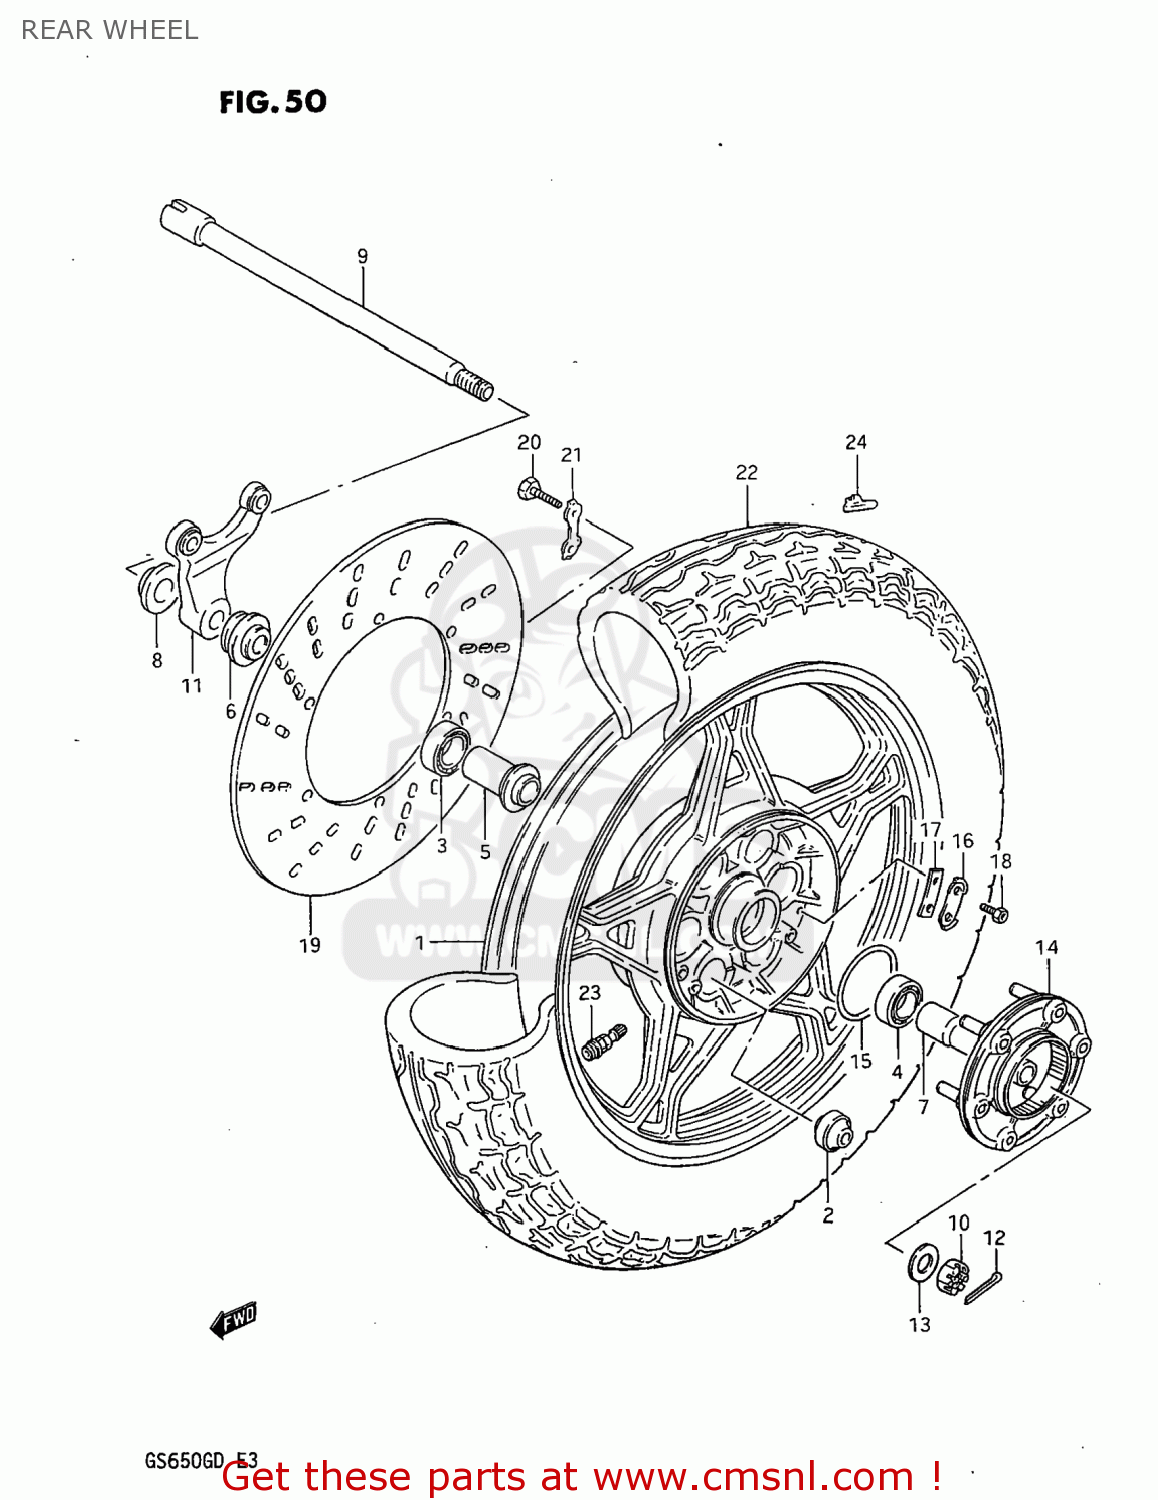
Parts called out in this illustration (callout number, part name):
1	CASTING WHEEL,REAR 2.50
2	BUSH
3	BEARING
4	BEARING
5	SPACER,REAR HUB BEARING
6	SPACER,REAR AXLE
7	SPACER,REAR AXLE,LEFT
8	SPACER,REAR AXLE,RIGHT
9	AXLE,REAR
10	NUT
11	BRACKET,RR,CALIPER
12	PIN,COTTER
13	WASHER(16.5X36X3.2)
14	JOINT ASSEMBLY,REAR HUB DRUM
15	O RING(D:2.1,ID:65)
16	WASHER
17	WASHER,THRUST(T:1.6)
18	BOLT(6X16)
19	DISC,RR BRAKE
20	BOLT(8X25)
21	WASHER
22	TIRE
23	VALVE ASSEMBLY,WHEEL RIM,J
24	BALANCER,WHEEL
